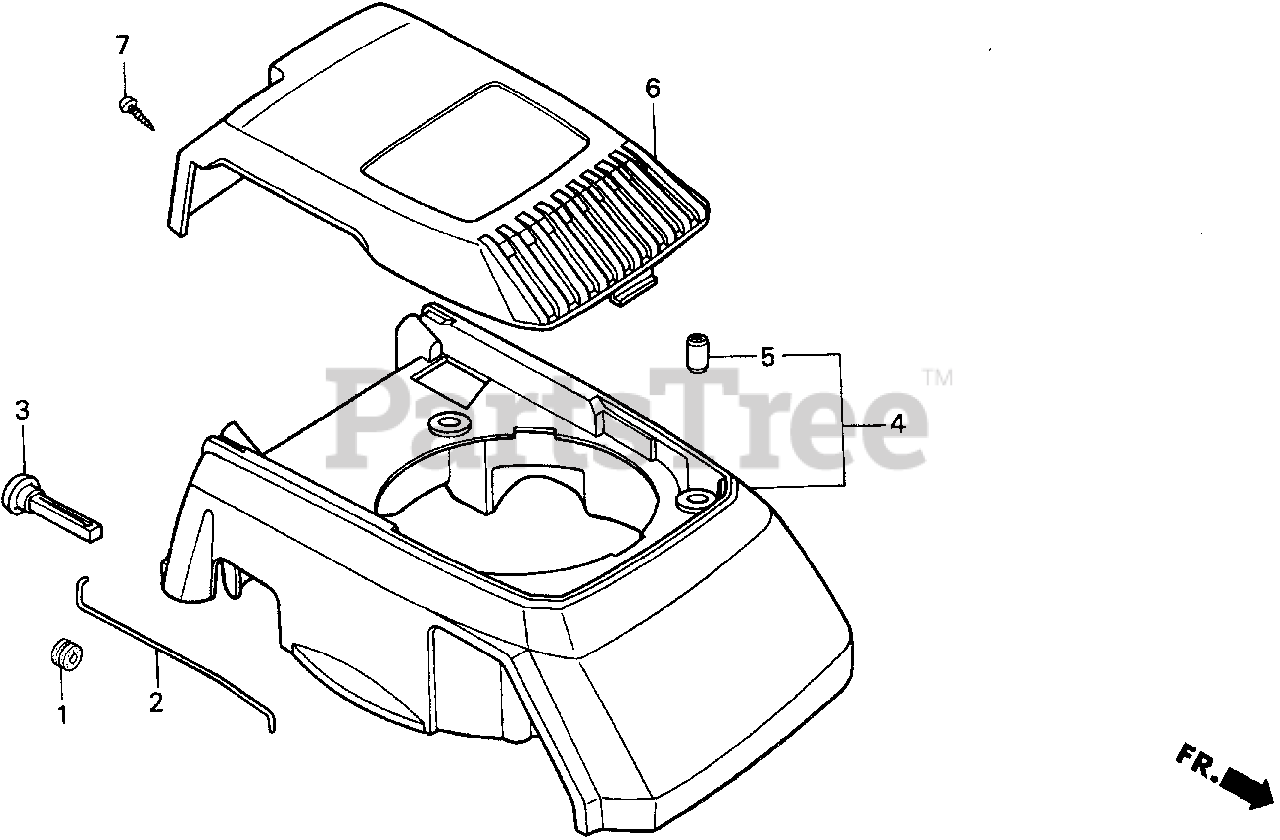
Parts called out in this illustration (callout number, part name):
1	GROMMET, CHOKE ROD
2	ROD, CHOKE
3	KNOB, CHOKE
4	COVER, FAN *R280* (POWER RED)
5	COLLAR, FAN COVER
6	HOOD, FAN COVER *NH31* (MCKINLEY WHITE)
7	SCREW, TAPPING (4X16)
